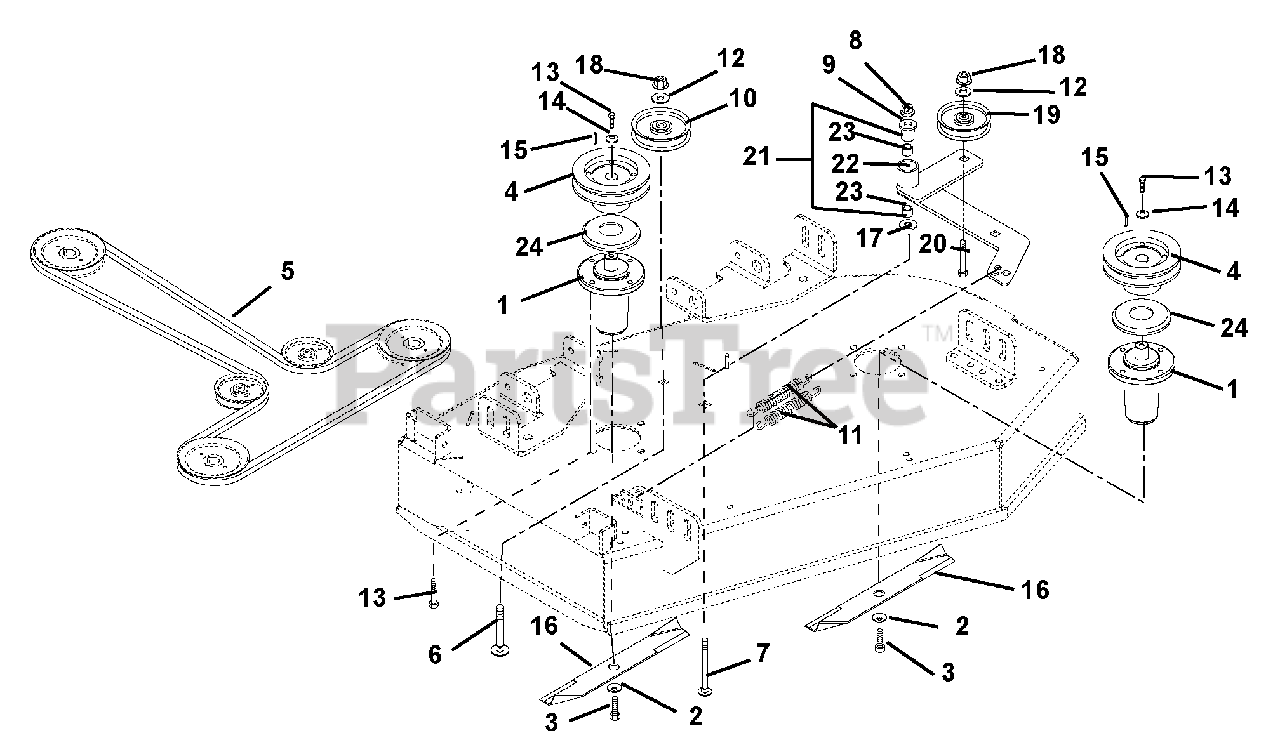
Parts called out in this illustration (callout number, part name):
1	Assembly, Maintenance Free Spindle
2	Washer-Bellville .63 x 1.625 x .14
3	Bolt-Hex .62-18 x 1.75 Grade 8
4	Sheave, 5.00 Spindle (1.00 I.D.)
5	V-Belt, B-Section 49.68 x .625
6	Bolt-Round Head Square Neck .38-16 x 2.75 Grade 5
7	Bolt-Round Head Square Neck .50-13 x 3.50 Grade 5
8	Nut, Nyloc Flange .50-13
9	Bearing, Pedestal Powdered Metal
10	Idler-Flat 4.00 x .38 (2.00 W)
11	Spring, Extension
12	Washer-Flat-Steel .375 x 1.125 x .065
13	Bolt-Hex .38-16 x 1.00 Grade 8
14	Washer-Flat-Steel .406 x 1.50 x .245
15	Key, Square .25 x .25 x 1.00
16	Blade, Mower Sand (314)
16	Blade, Mower Hi-Lift (056)
16	Blade, Mulching 50" Mower
17	Washer-Flat-Steel .563 x 1.38 x .109
18	Nut, Nyloc Flange 3/8-16
19	Idler, Flat 4.00 x .38 (1.00 W)
20	Bolt, Round Head Square Neck .38-16 x 2.00 Grade 5
21	Assembly, Idler Pivot Arm (Contains Items 22 & 23)
22	Weldment, Idler Pivot Arm
23	Bearing, 1.00 x 1.12 x .75
24	Slinger-Dust
